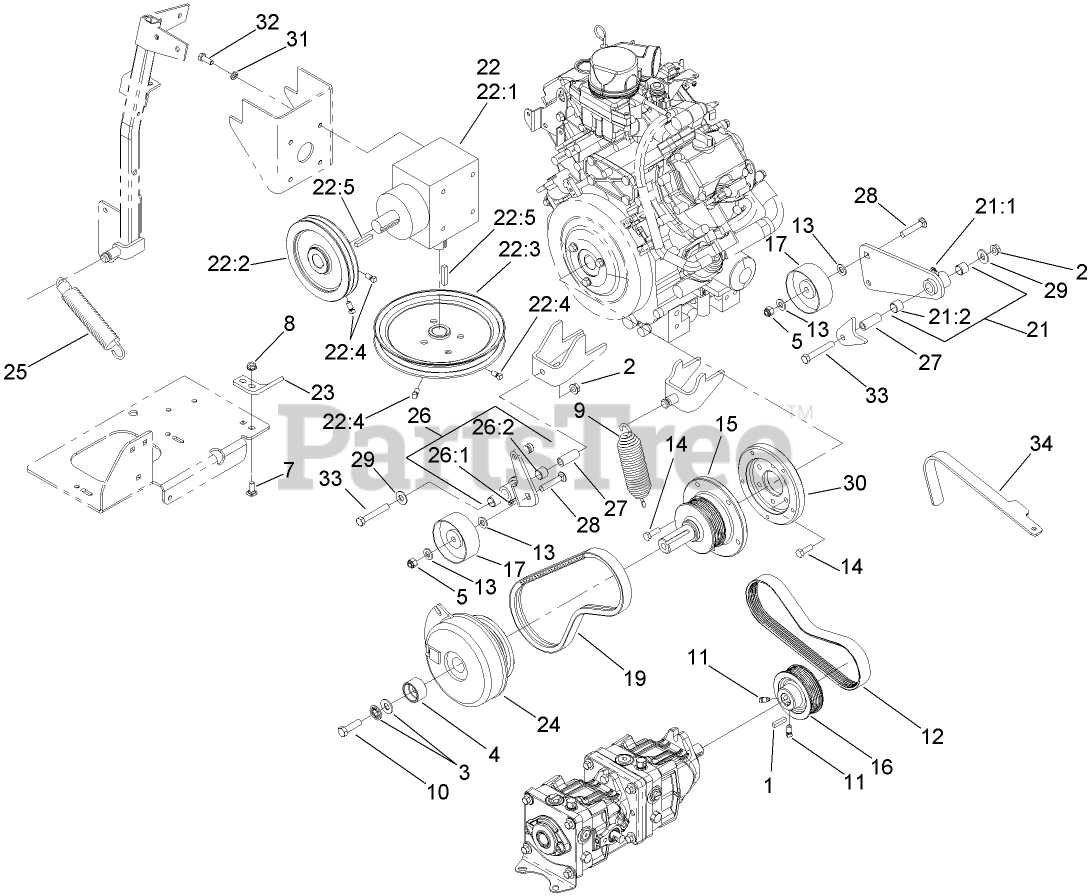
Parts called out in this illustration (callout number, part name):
2	NUT-HHF, WHIZ
3	WASHER-SPRING
4	RETAINER-CLUTCH
5	NUT-LOCK, NI
7	SCREW-CARR
8	NUT-HF
9	SPRING-EXTENSION
10	SCREW-HH
11	SCREW-SET
12	BELT-V
13	WASHER-FLAT
14	SCREW-HH
15	SHAFT-STUB
16	PULLEY
17	PULLEY-FLAT
19	BELT-V
21	IDLER ARM ASM
21:1	FITTING-GREASE
21:2	SLEEVE-BEARING
22	Gearbox ASM
22:1	GEARBOX-90 DEG
22:2	PULLEY
22:3	PULLEY
22:4	SCREW-SET
22:5	KEY-SQUARE
23	BRACKET-CLUTCH STOP
24	CLUTCH-ELECTROMAGNETIC
25	SPRING-IDLER, DECK
26	IDLER ARM ASM
26:1	FITTING-GREASE
26:2	SLEEVE-BEARING
27	BUSHING
28	SCREW-CARR
29	WASHER-FLAT
30	ADAPTER-STUB SHAFT
31	WASHER-LOCK
32	SCREW-HH
33	SCREW-HH
34	TOOL-ALIGNMENT, PULLEY
